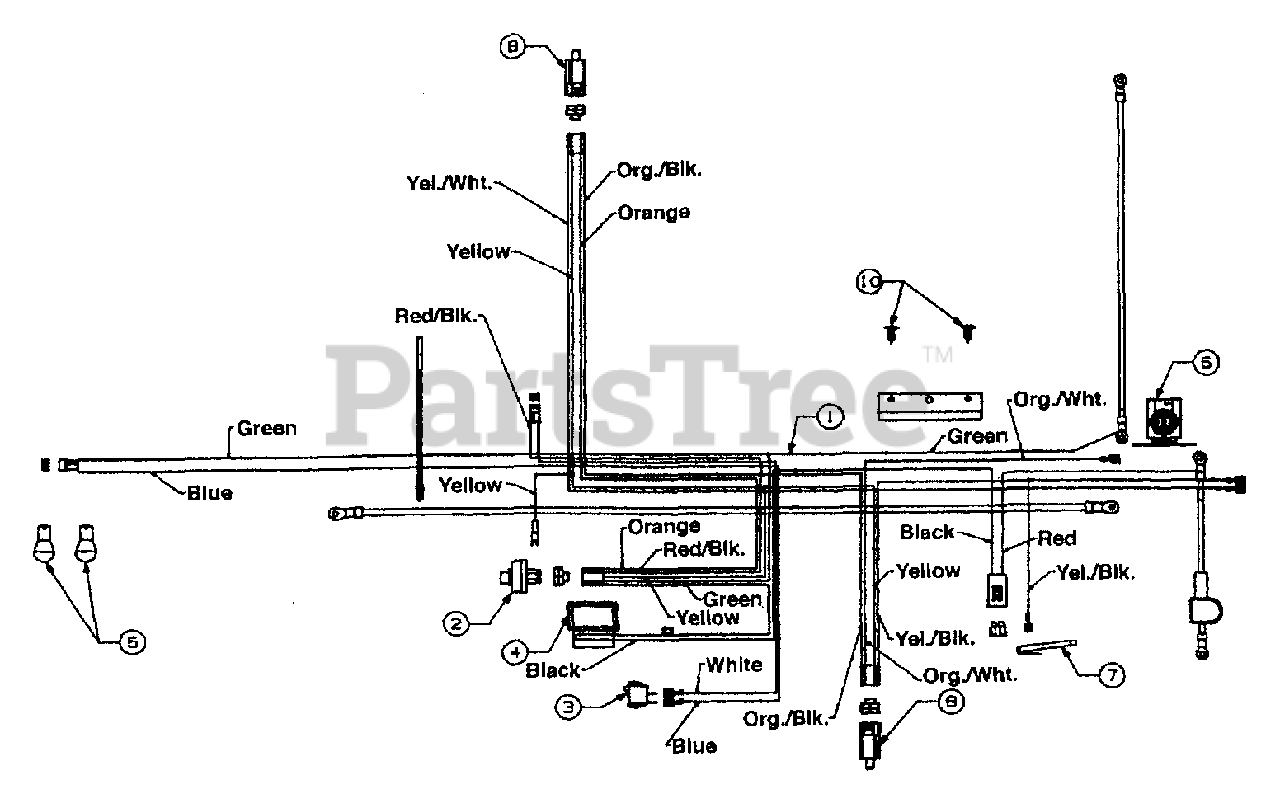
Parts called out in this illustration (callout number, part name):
1	Wire Harness w/Light Switch & Amp
2	Ignition Switch
3	Light Switch
4	Ammeter
5	Bulb (Headlight)
6	Solenoid
7	Safety Switch (Reverse)
8	Safety Switch
10	Ratchet
